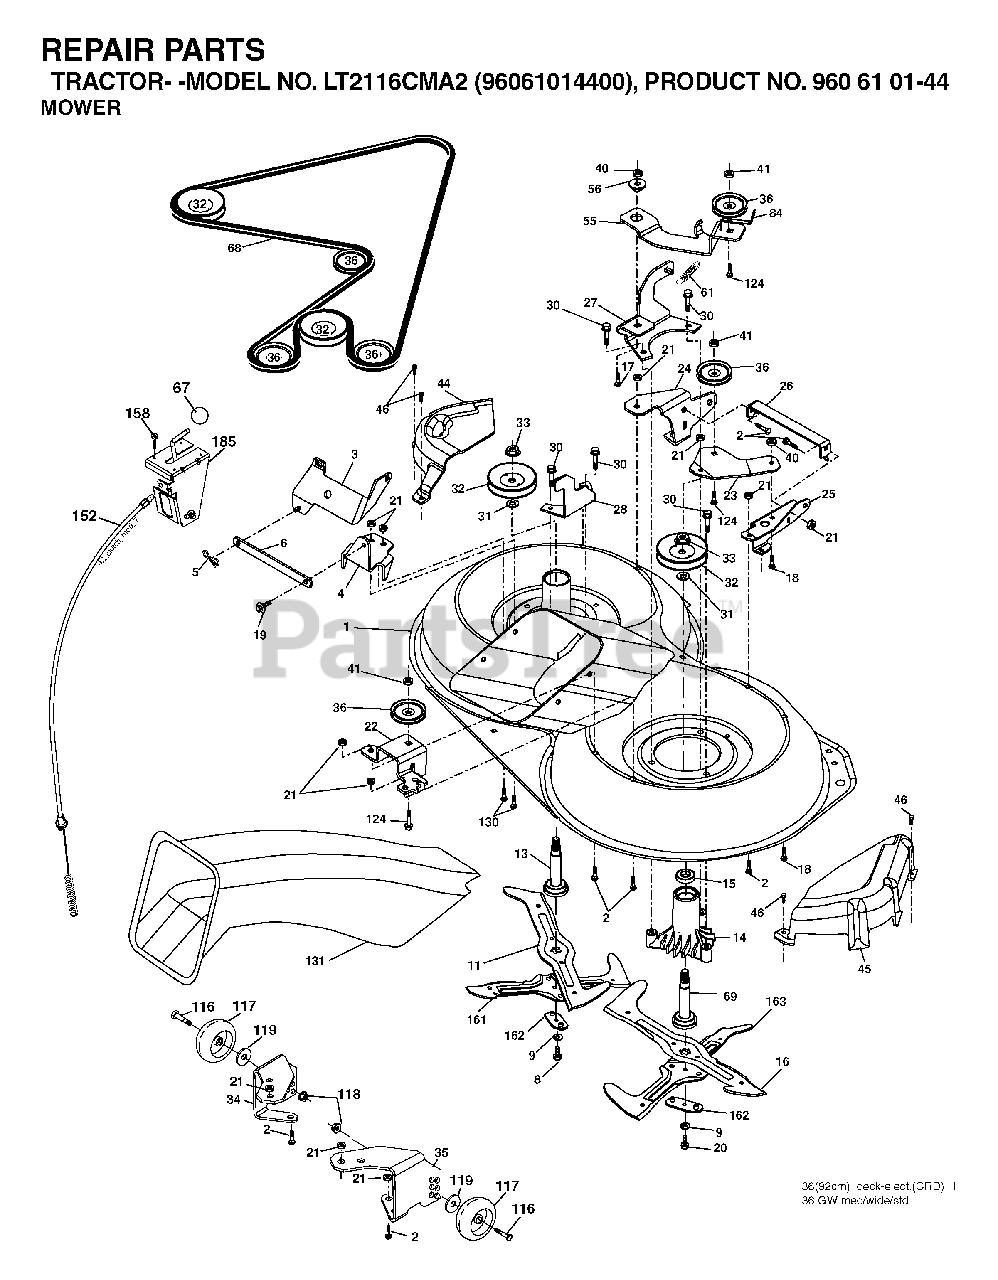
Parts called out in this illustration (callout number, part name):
2	BOLT
3	BRACKET
5	RETAINER-SPRNG RB
6	BAR SWAY
9	LOCKWASHER
13	SHAFT ASM VENT
14	HSG MANDREL
17	BOLT.3/8-14X1.25
19	BOLT SHD 5/16-18
21	LOCKNUT
24	BRACKET
25	BRACKET
28	BRACKET
30	SCREW, WASHER HEAD
31	WASHER.SPACER.MANDREL
33	NUT.FLANGE.LOCK.TOP
36	PULLEY.IDLER.4.25
40	LOCKNUT
41	NUT LOCK FLG 3/8-16 UNC
45	MANDREL COVER
46	SCREW.1/4-20X5/8
56	SPACER.RETAINER.MOWER
67	KNOB T (3/8 HOLE)
68	HEX-BELT
69	SHAFT.ASM.W/LWR.BRG.RH.THREAD
84	KEEPER, BELT IDLER
116	SHOULDER BOLT
117	WHEEL. GUAGE RALLY
118	LOCKNUT
119	WASHER
124	BOLT.3/8-16X1.50
131	CHUTE BAGGER
158	SCREW
185	HEAD ASM. CABLE CLUTCH
